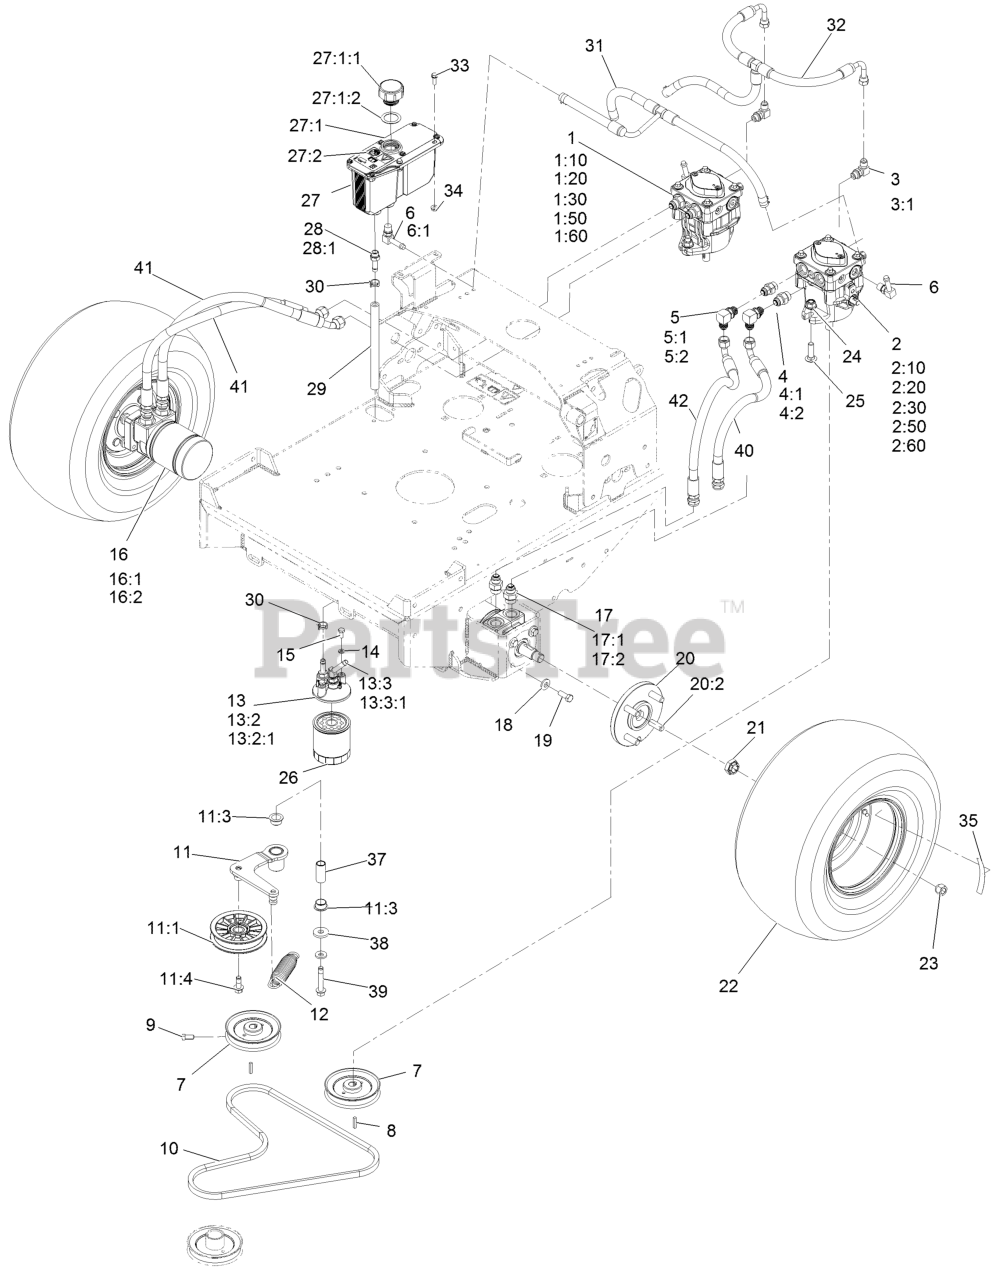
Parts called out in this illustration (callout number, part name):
1	PUMP-HYD PE RH TTH
1:10	INPUT SHAFT KIT
1:20	BEARING-THRUST
1:30	CYLINDER BLOCK KIT
1:50	SEAL OVERHAUL KIT
1:60	KIT, 10CC PUMP KIT
2	PUMP-HYD PE LH TTH
2:10	INPUT SHAFT KIT
2:20	BEARING-THRUST
2:30	CYLINDER BLOCK KIT
2:50	SEAL OVERHAUL KIT
2:60	KIT, 10CC PUMP KIT
3	FITTING-ELBOW, 90 DEG
4	FITTING-STRAIGHT
5	FITTING-90 DEG
6	FITTING-ELBOW, 90
6:1	O-RING
7	SHEAVE ASM
9	SCREW-SET, SQH
10	BELT
11	ASM, PUMP IDLER
11:1	PULLEY-IDLER, FLAT
11:3	BUSHING-FLANGE
11:4	SCREW-HFH
12	SPRING-EXTENSION
13	ASM, FILTER HEAD
13:2	ADAPTER-STRAIGHT
13:2:1	O-RING
13:3	FITTING-BARBED, 45 DEG
13:3:1	O-RING
14	WASHER-LOCK
15	SCREW-HH
16	HYD MOTOR ASM
16:1	SEAL KIT
16:2	BEARING AND SEAL KIT
17	FITTING-STRAIGHT
17:1	O-RING
18	WASHER-BELLEVILLE
19	SCREW-HH
20	WHEEL HUB ASM
20:2	STUD-WHEEL
21	NUT-LOCK
22	ASM, DRIVE TIRE
23	NUT-LUG
24	NUT-HF, NI
25	SCREW-HH
26	FILTER-25 MICRON, BI-DIRE
27:1	Reservoir-HYD
27:1:1	Cap-Reservoir, HYD
27:1:2	GASKET-CAP
27:2	DECAL-WARNING
28	ADAPTER-STRAIGHT
28:1	O-RING
29	HOSE,CASE DRAIN RH
30	CLAMP-HOSE
31	HOSE, CASE
32	HOSE, CHARGE
33	SCREW-HWH
35	DECAL-TORQUE WHEEL LUG-HU
37	PIVOT, IDLER
39	SCREW-HHF W/ PATCH
40	ASM, HP HOSE
41	HOSE,HYDRAULIC W/COVER
42	HYD HOSE ASM
